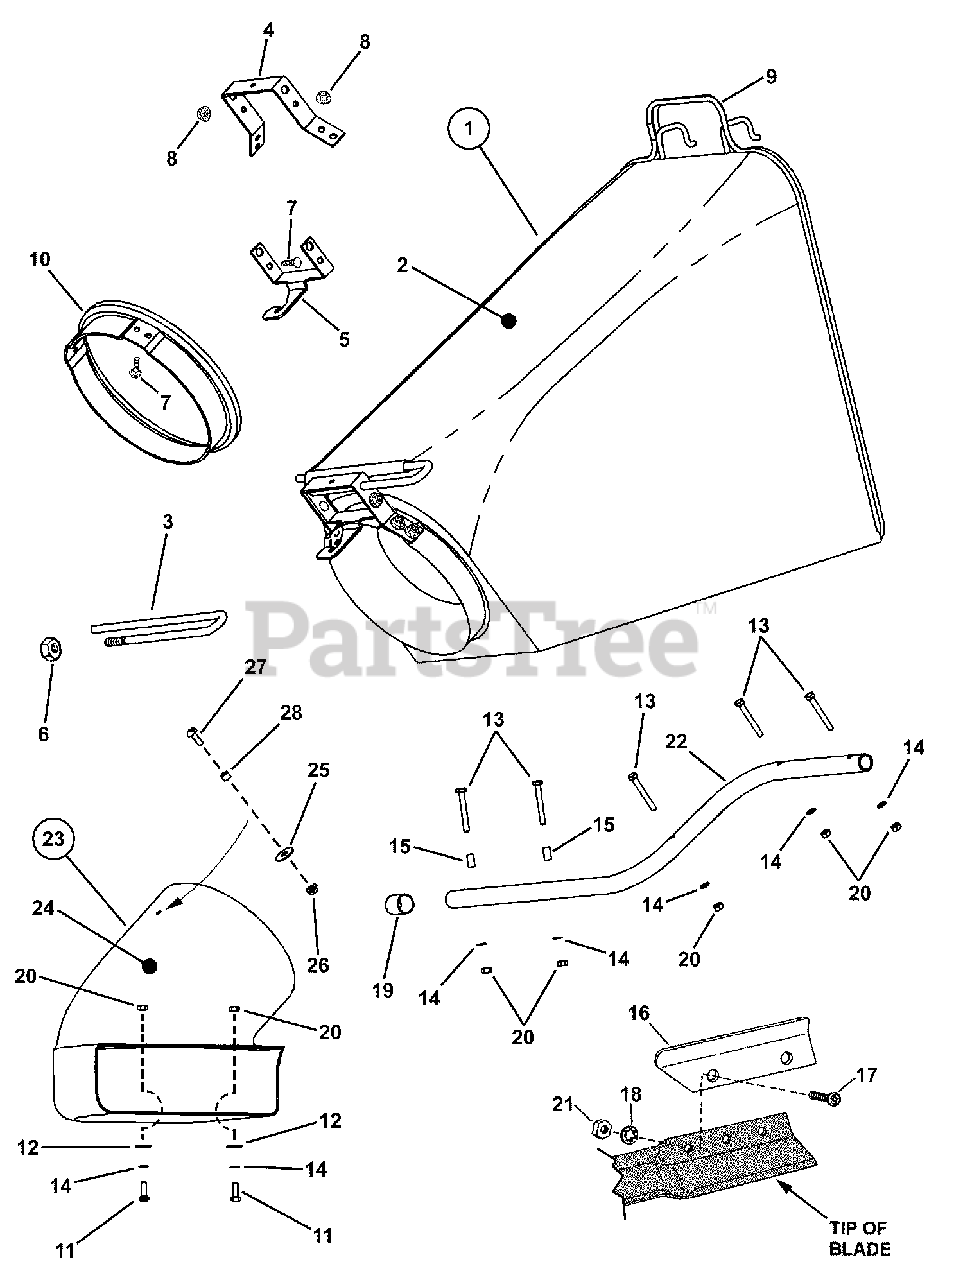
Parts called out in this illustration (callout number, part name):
1	ASSEMBLY, Grass Bag
2	GRASS BAG
3	FRONT BAG WIRE
4	ADAPTER HANDLE
5	LATCH, Connector
6	NUT, 3/8-24 Hex Center Lock, GR5 or B
7	BOLT, 1/4-20 x 5/8" Flat Head Square Neck, GR5
8	NUT, 1/4-20 Hex Flange Lock
9	ASSEMBLY, Bag Wire
10	RING, Grass Bag Connector
11	SCREW, 1/4-28 x 3/4, Hex Head Cap, GR5
12	WASHER, 5/16 x 3/4 x .08 Flat
13	SCREW, 1/4-28 x 2" Hex Head Cap, GR5
14	WASHER, 1/4" Internal Tooth Lock
15	SPACER, .255 x .640
16	EXTENSION, Air Lift
17	SCREW, 5/16-24 x 21/32" Oval Head Machine, Cross Recess
18	WASHER, 5/16 Internal Tooth Lock
19	CAP, Plastic
20	NUT, 1/4-28 Hex, Grade 5 or B
21	NUT, 5/16-24 Hex, GR5 or B
22	TUBING, Bag Support
23	ADAPTER, Chute Assembly
24	ASSEMBLY, Grass Chute
25	FENDER WASHER, 5/16"
26	NUT,1/4-20 Hex Top Lock Flange, Grade B
27	SCREW,1/4-20 x 3/4" Round Head Machine
28	SPACER, .265 I.D. x .3 long
